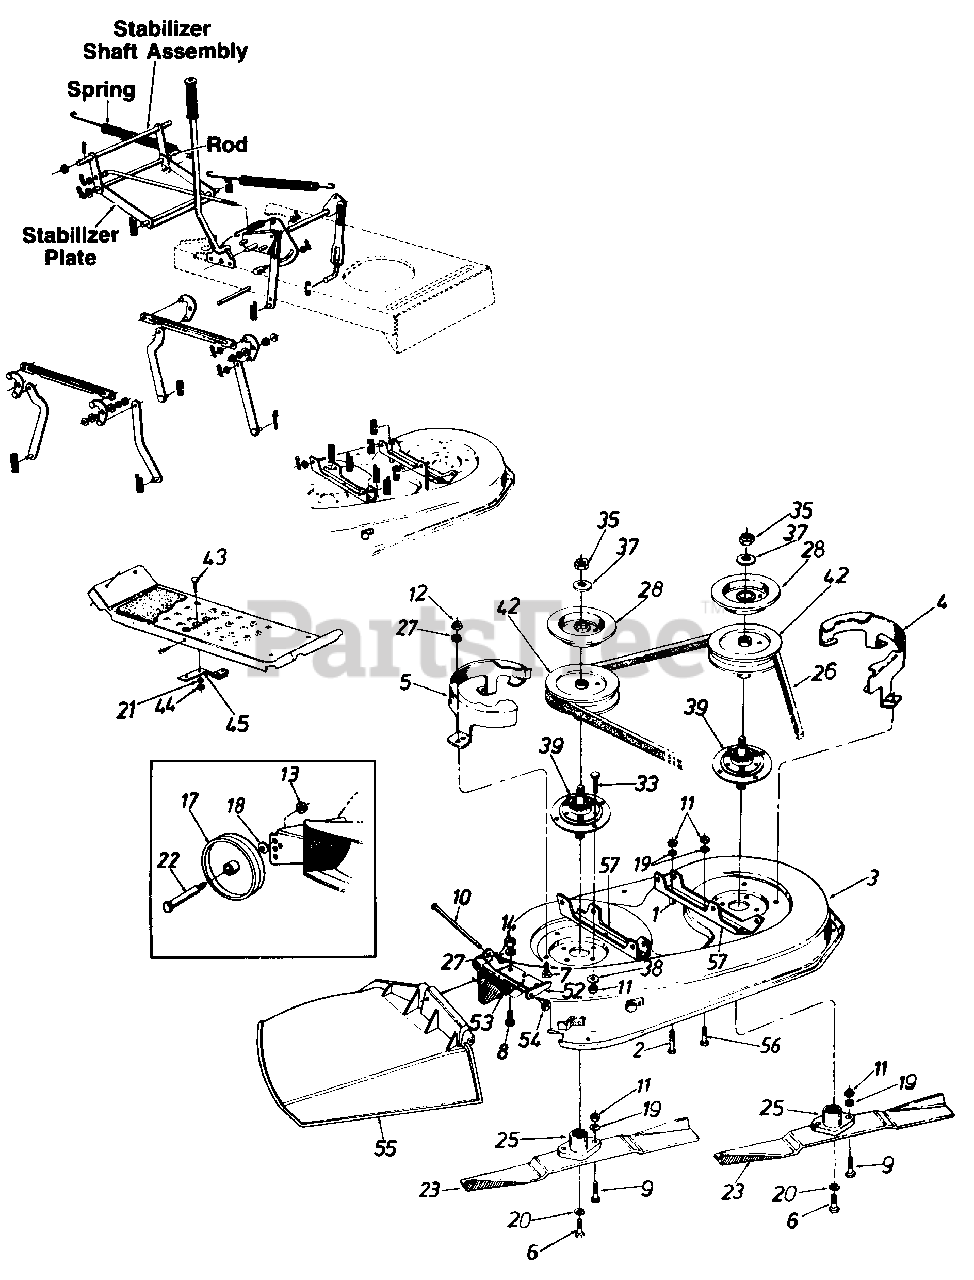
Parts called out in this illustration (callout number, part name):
1	Spacer.33" 1.0. x.88"
2	Hex Bolt 5/16-24 x 1.25" Lg.
3	38" Deck Ass'y. w/Deck Wheels
7	Hex 3dt 1/4-28 x .62" Lg.
8	Truss Mach. Scr. 1/4-20 x .75
9	Hox Bolt Special 5/16 24 x 1.0
10	Hinge Pin
11	Hex Nut 5/16-24 Thd.*
12	Hox Nut 1/4-28 Thd.
13	Hex Top L-Nut 3/8-16 Thd.
14	Hox Nut 1/4-20 Thd.*
17	Deck Wheel-5"
18	Bell-Wash. .40" I.D. x .88 O.D.
19	L-Wash. 5/18" I.D.*
20	L-Wash. 3/8" I.D.-H.D.
21	L-Wash. 1/4" I.D.*
22	Shld. Bolt .498" Dia x 1.53
23	High-Lift Blade
25	Blade Adapter
26	V-Belt
27	Bell-Wash l/4" I.D.
28	Brake Disc
33	Hex Bolt 5/16-24 x 75" Lg.
35	Hex Jam Nut 5/8-18 Thd.
37	L-Wash 5/8" I.D.
38	L-Wash 5/16" I.D.*
39	Blad-Spindle Ass'y Comp
42	5" Dia. Pulley
43	Carr Bolt 1/ 20 x 62"
44	Hox Nut 1/4-20 Thd.
45	Blade Brake Ass'y.
52	Hinge Mtg. Brkt.
53	Torsion Spring
54	Push Nut
55	Chute Ass'y Comp
56	Hox Bolt 5/1-24 x 75" Lg.
